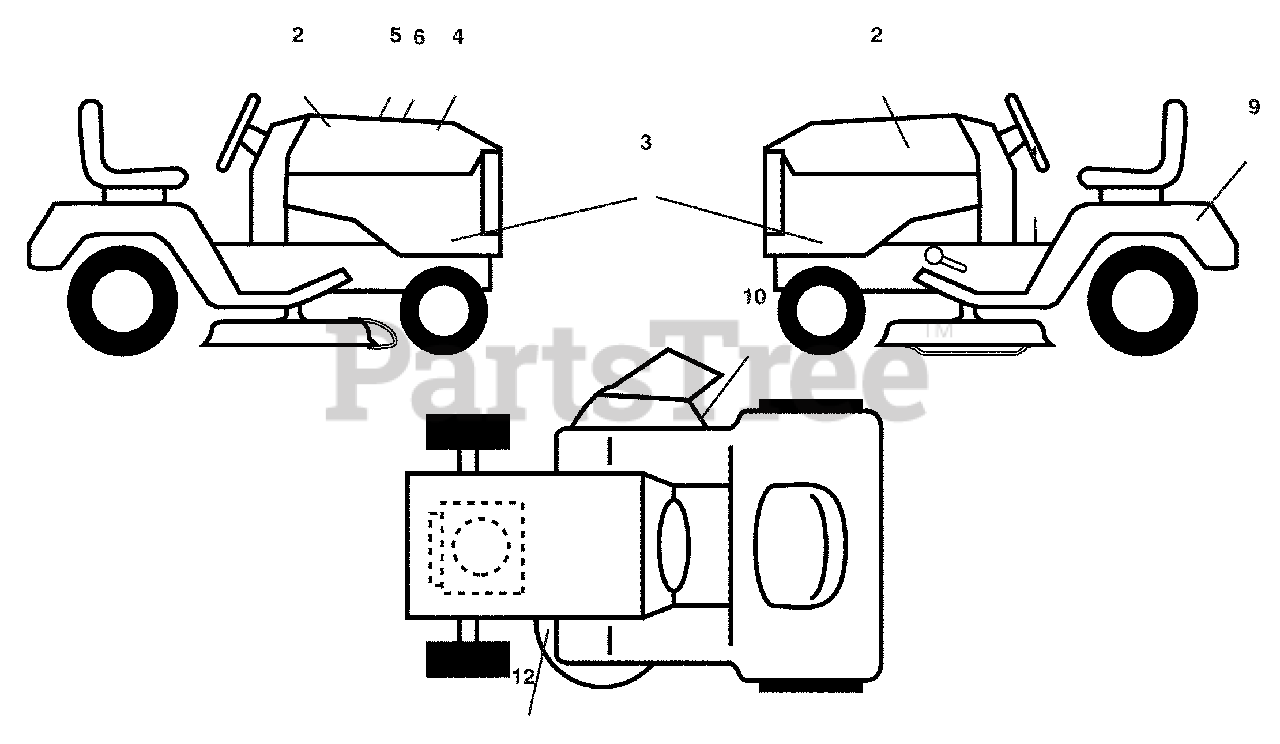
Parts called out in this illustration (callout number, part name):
1	Decal, Warning
2	Decal, Hood
3	Decal, Hood Panel SD
4	Decal, Ethanol E85 Warning
5	Decal, Customer Respons.
6	Decal, Replacement
9	Decal, Battery Dnge/Poi
10	Decal, Warning
12	Decal, Mower V-Belt Schematic
